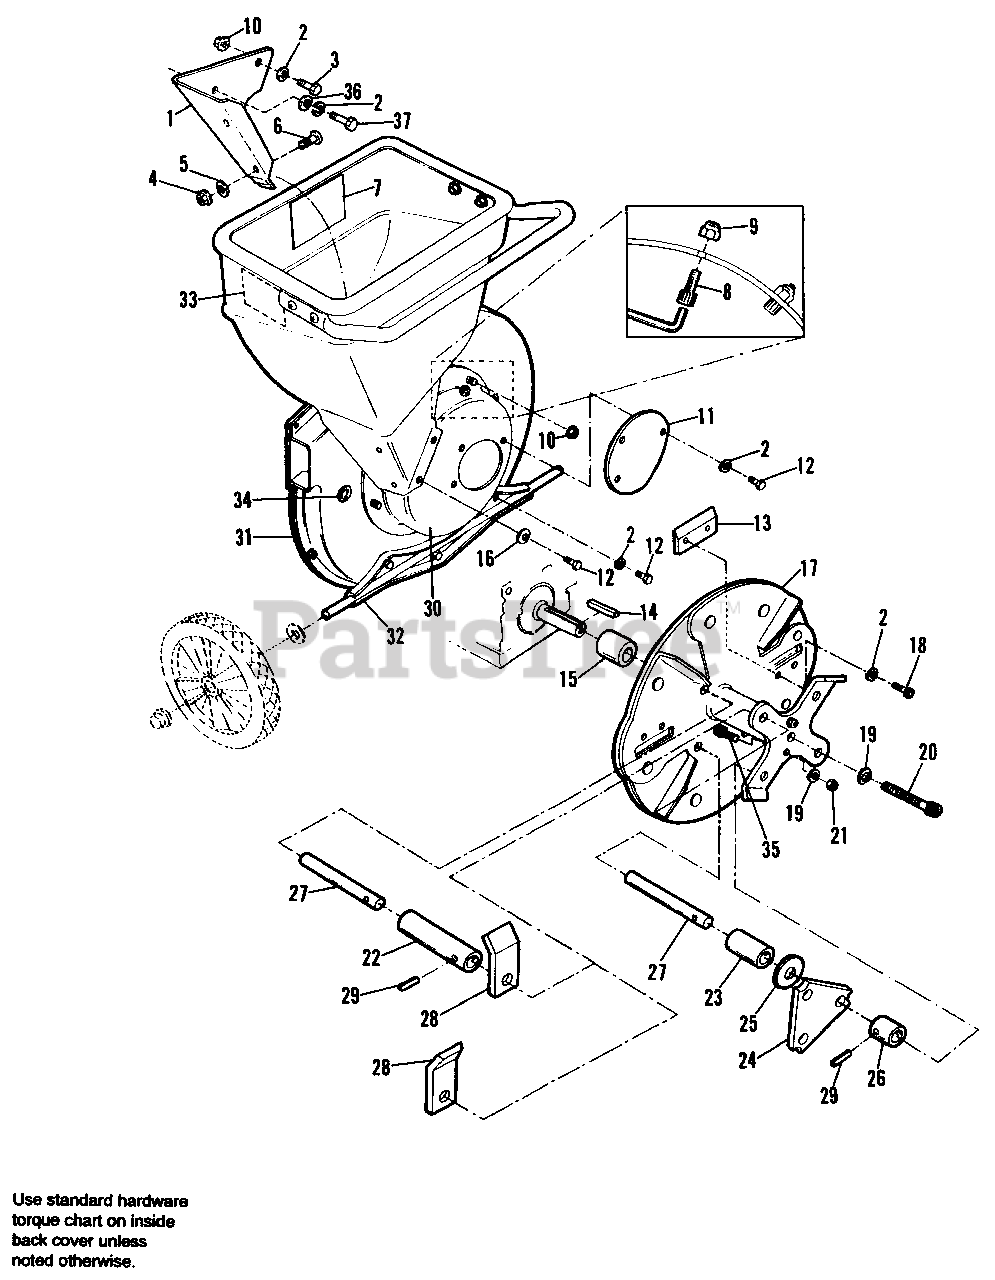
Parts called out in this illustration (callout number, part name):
1	HOPPER LINER
2	LOCKWASHER, Split, 5/16
3	CAPSCREW, Hex Hd., 5/16-18 x 1
4	NUT, 2-Way Lock, 1/4-20
5	WASHER, Flat, 1/4
6	CAPSCREW, Phillips Hd., 1/4-20 x 5/8
7	DECAL, CAUTION
8	CAPSCREW, Socket Hd., 5/16-18 x 1/2
9	NUT, Nylock, 5/16-18
10	NUT, Flange, Hex, 5/16-18
11	COVER, Rotor Housing
12	CAPSCREW, Hex Hd., 5/16-18 x 1/2
13	CHIPPER KNIFE
14	KEY, 1/4 Sq. x 1-7/8
15	SPACER, Rotor, 1"
16	WASHER, Fat, 5/16
17	ROTOR, 1" Hub
18	CAPSCREW, Socket Hd., 5/16-24 x 5/8
19	LOCKWASHER, Split, 3/8
20	CAPSCREW, Socket Hd., 3/8 24 x 2
21	NUT, Hex, 3/8 16
22	SPACER, Tube, 2-1/2" Long
23	SPACER, 1-5/8" Long
24	HAMMER, Triangular
25	WASHER, Flat, 1/2
26	SPACER, 13/16" Long
27	SHAFT, Hammer
29	ROLL PIN, 3/16 x 3/4
30	HOUSING, Rotor
31	HOUSING, Fan
32	AXLE ASSEMBLY
33	DECAL, Danger
34	PLUG BUTTON
35	CAPSCREW, Socket Hd., 3/8-16 x 5/8
36	WASHER, Flat, 5/16
37	CAPSCREW, Hex Hd., 5/16-18 x 3/4
